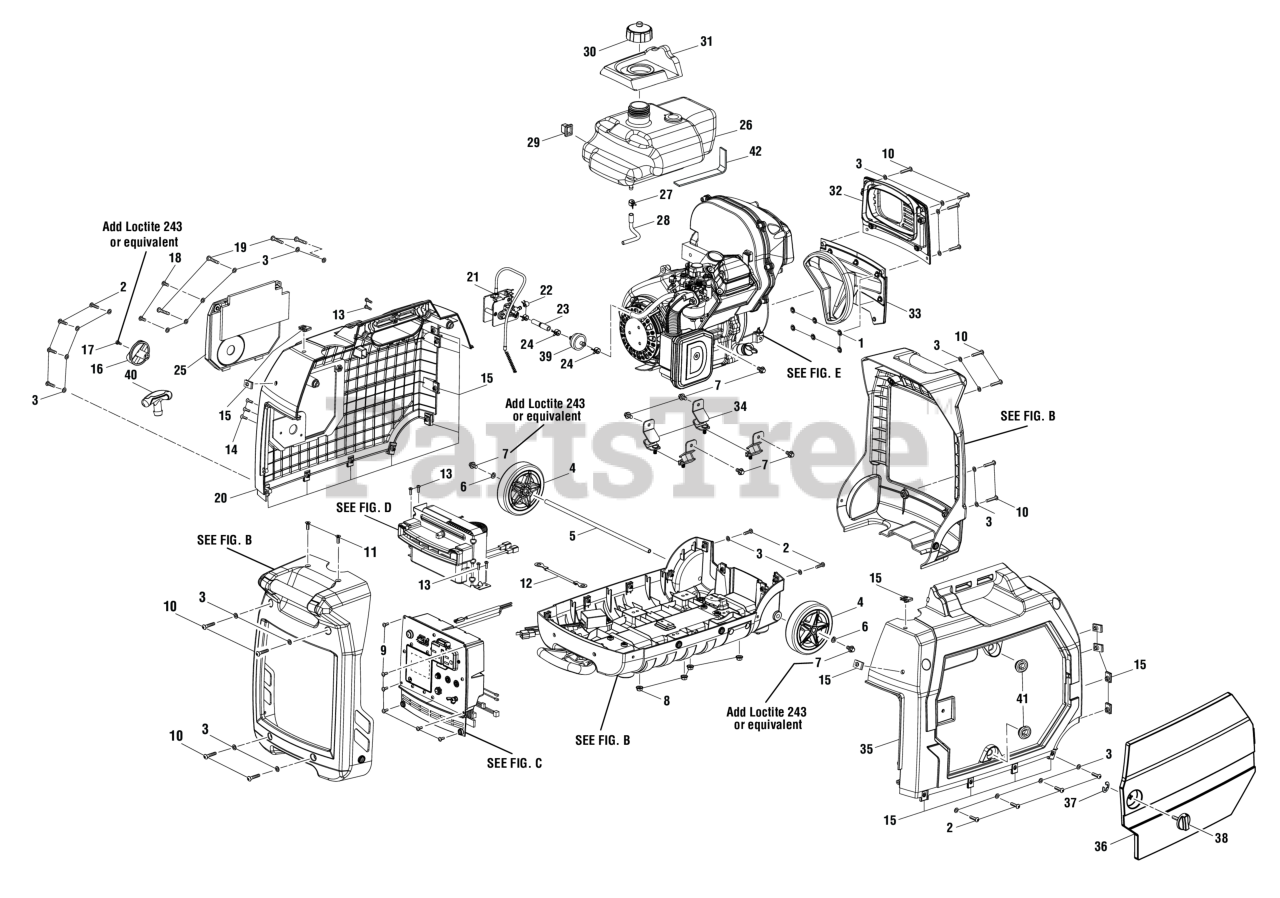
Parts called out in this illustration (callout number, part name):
1	Internal Tooth Strip Retainers
2	Screw (M5 x 20 mm, Button Soc. Hd.)
3	Washer (ID5.3 x OD10 x 1t)
6	Lock Washer (1/4 in.)
7	Bolt (M6 x 12 mm, Hex Hd.)
8	Lock Nut (M6)
9	Screw w/Washer (M4 x 10 mm, T20 Torx Button Hd.)
10	Screw (M5 x 25 mm, Button Soc. Hd.)
11	Screw (M5 x 16 mm, Flat Hd.)
12	Ground Wire
13	Screw (M4 x 12 mm, T15 Torx Pan Hd.)
14	Screw (M4 x 16 mm, Flat Hd.)
15	U-Clip (M5)
16	Control Knob
17	Screw (M4 x 10 mm)
18	Screw (M5 x 12 mm, T25 Torx Pan Hd.)
19	Screw (M5 x 30 mm, T25 Torx Pan Hd.)
20	Left Housing Assembly
21	Engine Start/Stop Mechanism Assembly
22	Fuel Line Clamp (3/8 in.)
23	Fuel Hose (4.5 mm and 6 mm)
24	Fuel Hose Clamp (9.5 mm)
25	Starter Cover Assembly
26	Fuel System Assembly
27	Clamp (D10 x 0.8 mm)
28	Fuel Hose (6mm and 4.5 mm)
29	Support (Fuel Tank)
30	Vented Fuel Cap
31	Overspill Guard
32	Upper Exhaust Panel Assembly (Inc. Key No. 3)
33	Lower Exhaust Panel Assembly
34	Engine Isolator (45 Degree)
35	Right Housing Assembly
36	Maintenance Cover Assembly
37	E-Clip (5 mm Shaft)
38	Lock Knob
39	Fuel Filter Inline (1/4 in.)
40	Recoil Handle
42	Rubber Pad
